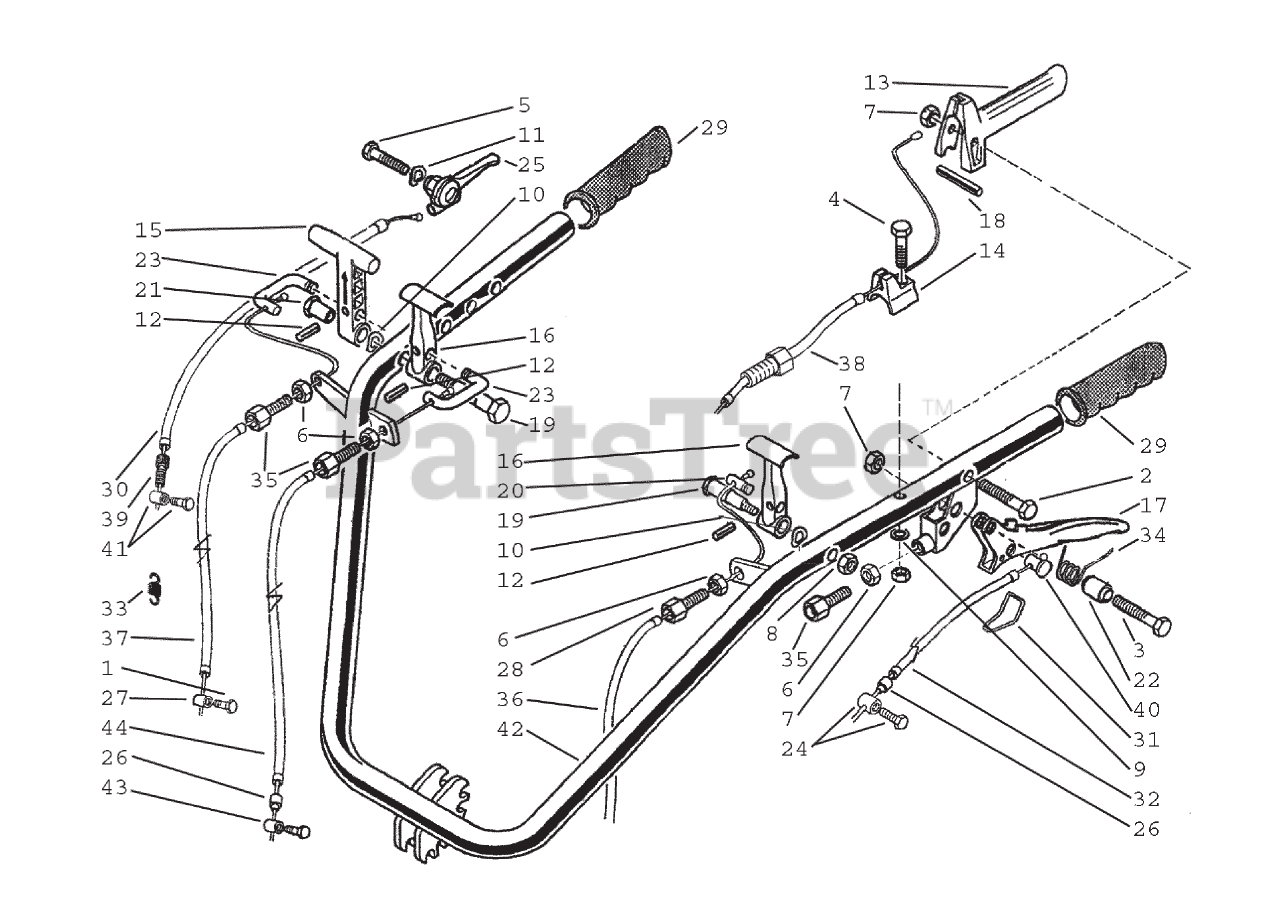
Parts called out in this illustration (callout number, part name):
1	CAP SCREW, M6X14
2	CAP SCREW, M6X45
3	CAP SCREW, M6X25
4	CAP SCREW, M6X35
5	CAP SCREW, M8X35
6	NUT, M8
7	LOCK NUT, M6
8	LOCK NUT, M8
9	FLAT WASHER, M6
10	FLAT WASHER, M8
11	LOCK WASHER, M8.4
12	PIN, SPLIT, M4 X 20 SPIROL
13	LEVER, MOTOR STOP
14	GUIDE, CABLE
15	LEVER, REVERSER
16	LEVER, DIFF/ STEERING RELEASE
17	LEVER, CLUTCH
20	DRILLED PIN
21	BUSHING, REVERSE LEVER
22	LEVER, SPACER
23	PIN, REVERSE CABLE
24	CABLE CLAMP
25	ACCELERATOR LEVER
26	SHEATH END
27	CLAMP
28	SCREW, ADJUSTING M8
30	CABLE, ACCELERATOR, 73SHX79
31	STOP WIRE
32	CABLE AND SHEATH, CLUTCH
33	SPRING
34	SPRING
35	SCREW, ADJUSTMENT
36	CABLE & SHEATH, STEERING COLUMN RELEASE
37	CABLE AND SHEATH, REVERSE
38A	CABLE, MOTOR STOP - SHEATH LENGTH =24.5"
38B	CABLE, MOTOR STOP - SHEATH LENGTH =29.5"
39	SCREW, ADJUSTING M6
40	BARREL
41	CLAMP
42	HANDLEBAR
43	CABLE CLAMP
44	CABLE AND SHEATH, DIFFERENTIA
